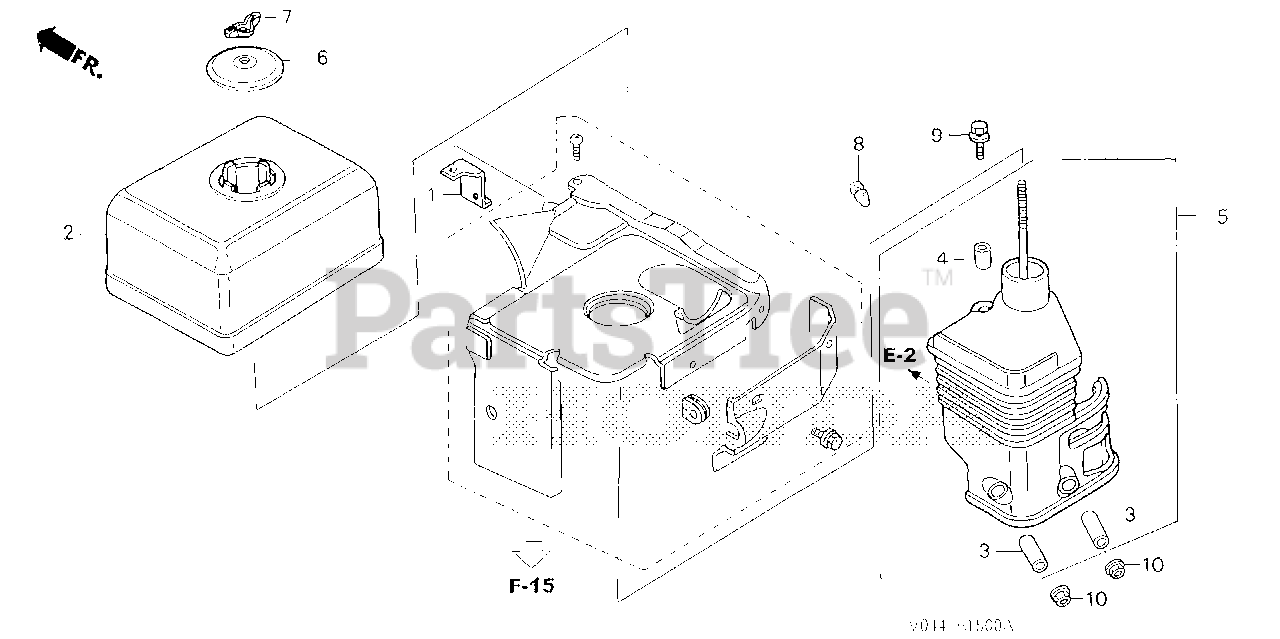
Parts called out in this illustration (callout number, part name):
1	STAY, ENGINE CONTROL COVER
2	COVER, AIR CLEANER (SEMI-DRY)
3	COLLAR, AIR CLEANER
4	COLLAR B, AIR CLEANER
5	ELBOW, AIR CLEANER
6	CAP, AIR CLEANER
7	NUT, TOOL BOX SETTING
8	PLUG, CONE TYPE
9	BOLT, FLANGE (6X20)
10	NUT, FLANGE (6MM)
